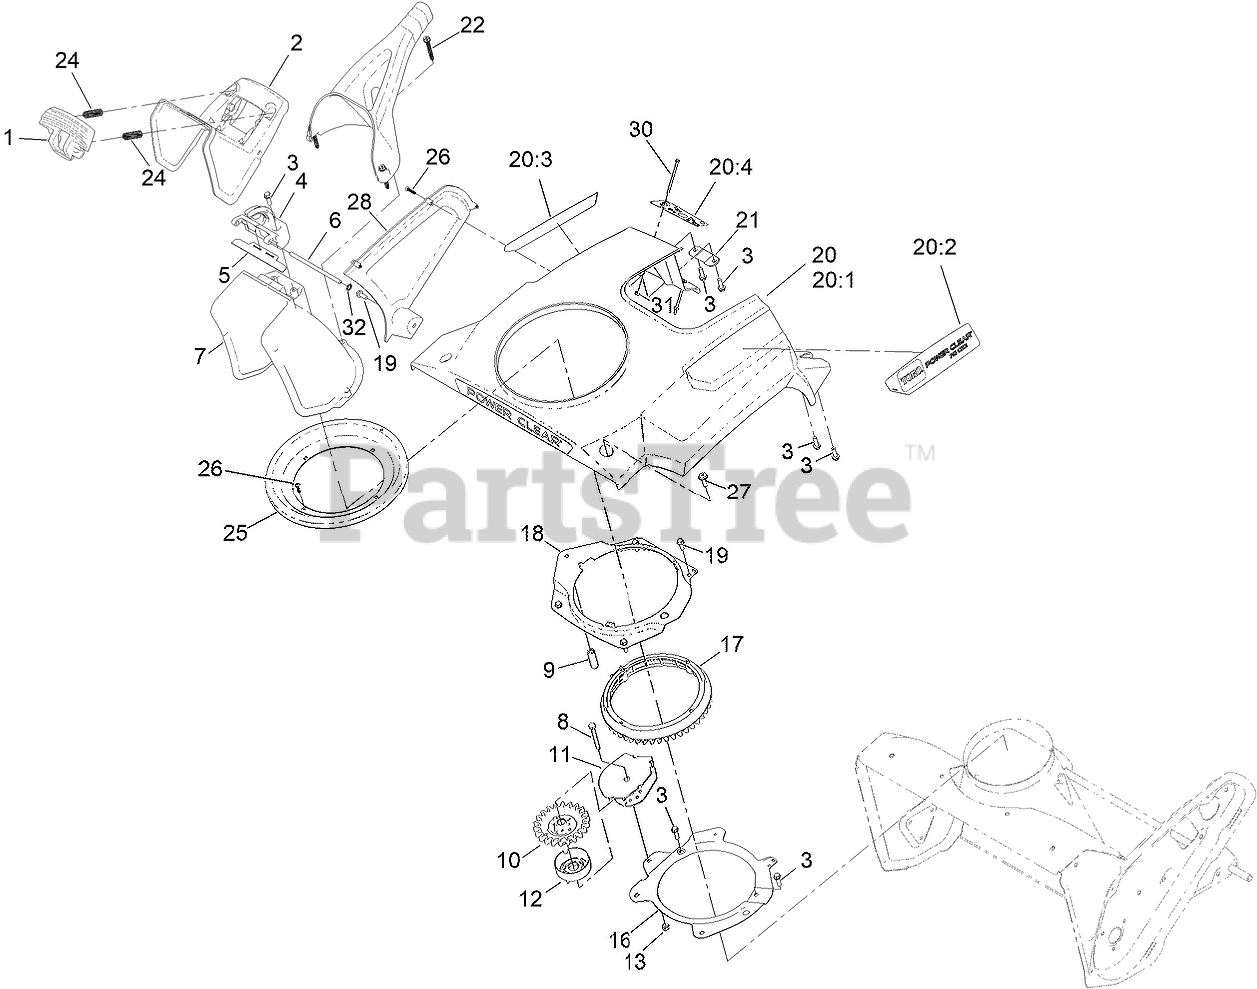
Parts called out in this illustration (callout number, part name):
1	TRIGGER-DEFLECTOR
2	DEFLECTOR-CHUTE, CE
3	SCREW-HWH
4	HINGE-RATCHET, DEFLECTOR
5	SEAL-DEFLECTOR
6	HINGE PIN-DEFLECTOR
8	SCREW-HH
9	SPACER-SLEEVE, PINION
10	PINION-GEAR
11	BRACKET-PINION
12	RETAINER-CABLE
13	NUT-LOCK, NI
16	RING-SUPPORT, CHUTE
17	RING-CHUTE, GEAR
18	RETAINER-RING, CHUTE
19	SCREW-HWH
20	SHROUD ASM, W/DECALS
20:1	SHROUD ASM, W/ARTWORK
20:2	DECAL- SHROUD LH
20:3	DECAL-SHROUD RH
20:4	DECAL-ENGINE, ELECTRIC START
21	RETAINER-SHROUD
22	SCREW-PLASTITE
24	SPRING-COMPRESSION
25	SEAL-RING, CHUTE
26	SCREW-PPH
27	SCREW-PPH
28	COVER-SIDE
30	SCREW-HWH
31	NUT-HEX
32	RING-RETAINING
